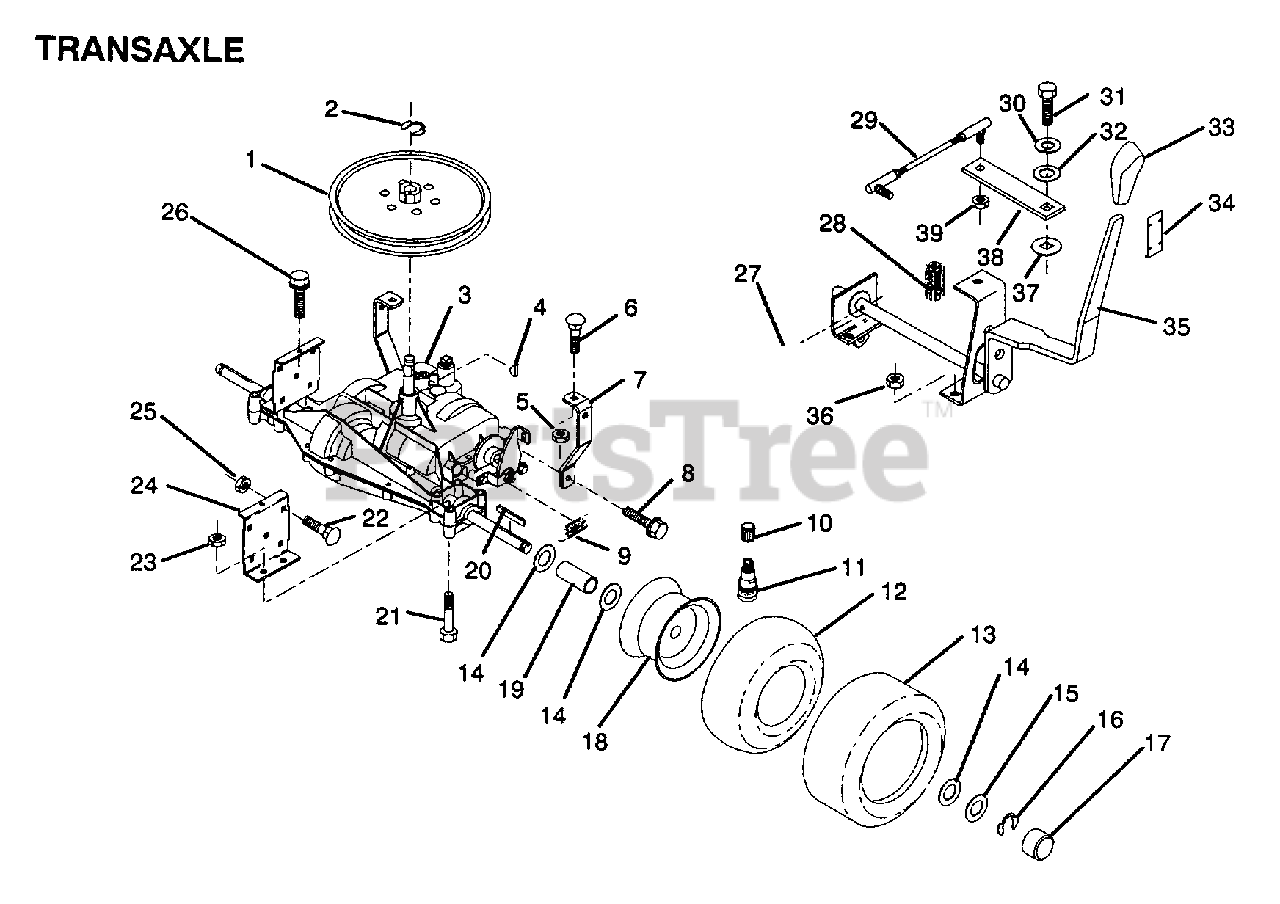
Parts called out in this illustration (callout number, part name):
1	PULLEY
6	BOLT
7	"STRAP,TORQUE"
8	SCREW LT
10	VALVE CAP
11	VALVE STEM LT
12	TUBE.16X6.5/7.5-8
13	TIRE.16X7.5-8
14	WASHER
15	WASHER
16	E-RING LT
17	HUB CAP
19	SPACER
20	SQUARE KEY
21	BOLT
22	BOLT
24	"BRKT,TRANSAXLE"
26	SCREW
27	PIN COTTER 1/8
28	EXT SPRING
29	"LINK,SHIFT"
30	LOCKWASHER
32	WASHER LT
33	"KNOB,SHT CONTROL"
34	KNOB RETAINER
35	SHIFT HANDLE ASSY
37	WASH-SHFT PLT LT
38	"ARM,SHIFT"
39	NUT.LOCK.5/16-24
